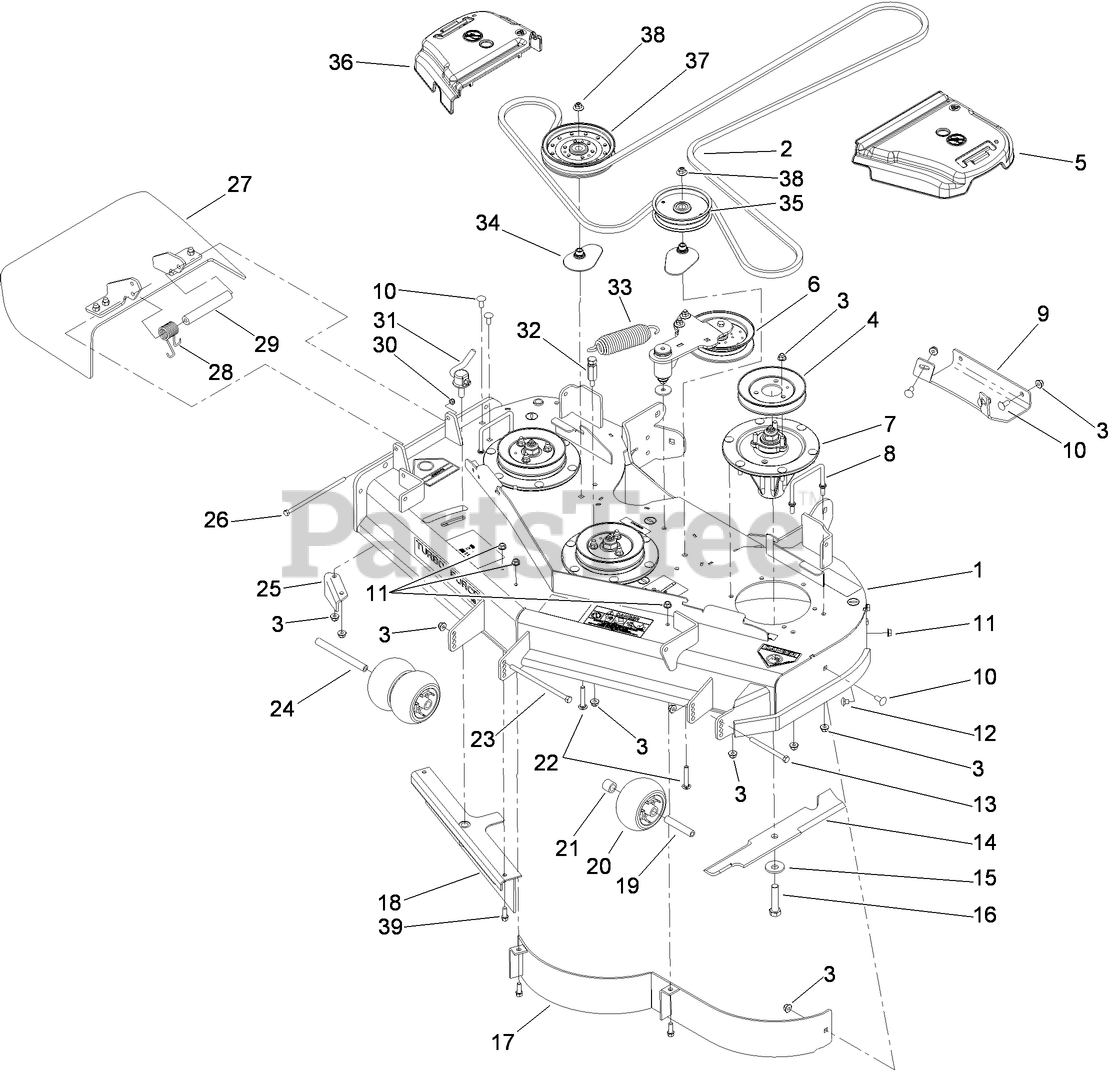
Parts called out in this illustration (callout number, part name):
1	DECK DECAL ASM
2	BELT-V
3	NUT-HF, NI
4	PULLEY
5	COVER-BELT, LH
6	IDLER ARM ASM
7	SPINDLE ASM
8	WIREFORM-COVER
9	PLATE-SKID
10	SCREW-CARR
11	NUT-HHF, WHIZ
12	SCREW-CARR
13	SCREW-HH
14	BLADE-16.5 INCH (HIGH FLOW)
15	Washer-Blade Bolt, Heavy
16	SCREW-BLADE
18	BAFFLE
19	TUBE-SPANNER
20	ROLLER-SCALP, ANTI
21	TUBE-SPACER
22	BOLT-CARR, SHORT NECK
23	SCREW-HH
24	SPACER-WHEEL
25	BAFFLE-DISCHARGE
26	SCREW-HH
27	RUBBER DEFLECTOR ASM
28	SPRING-TORSION
29	SPACER
30	NUT-LOCK, NI
31	LEVER ASM
32	ANCHOR-SPRING, TALL
33	EXTENSION-SPRING
34	SPACER-PULLEY
35	PULLEY-IDLER
36	COVER-BELT, RH
37	PULLEY-IDLER, FLAT
38	NUT-FLANGE, NI
39	SCREW-HWH
